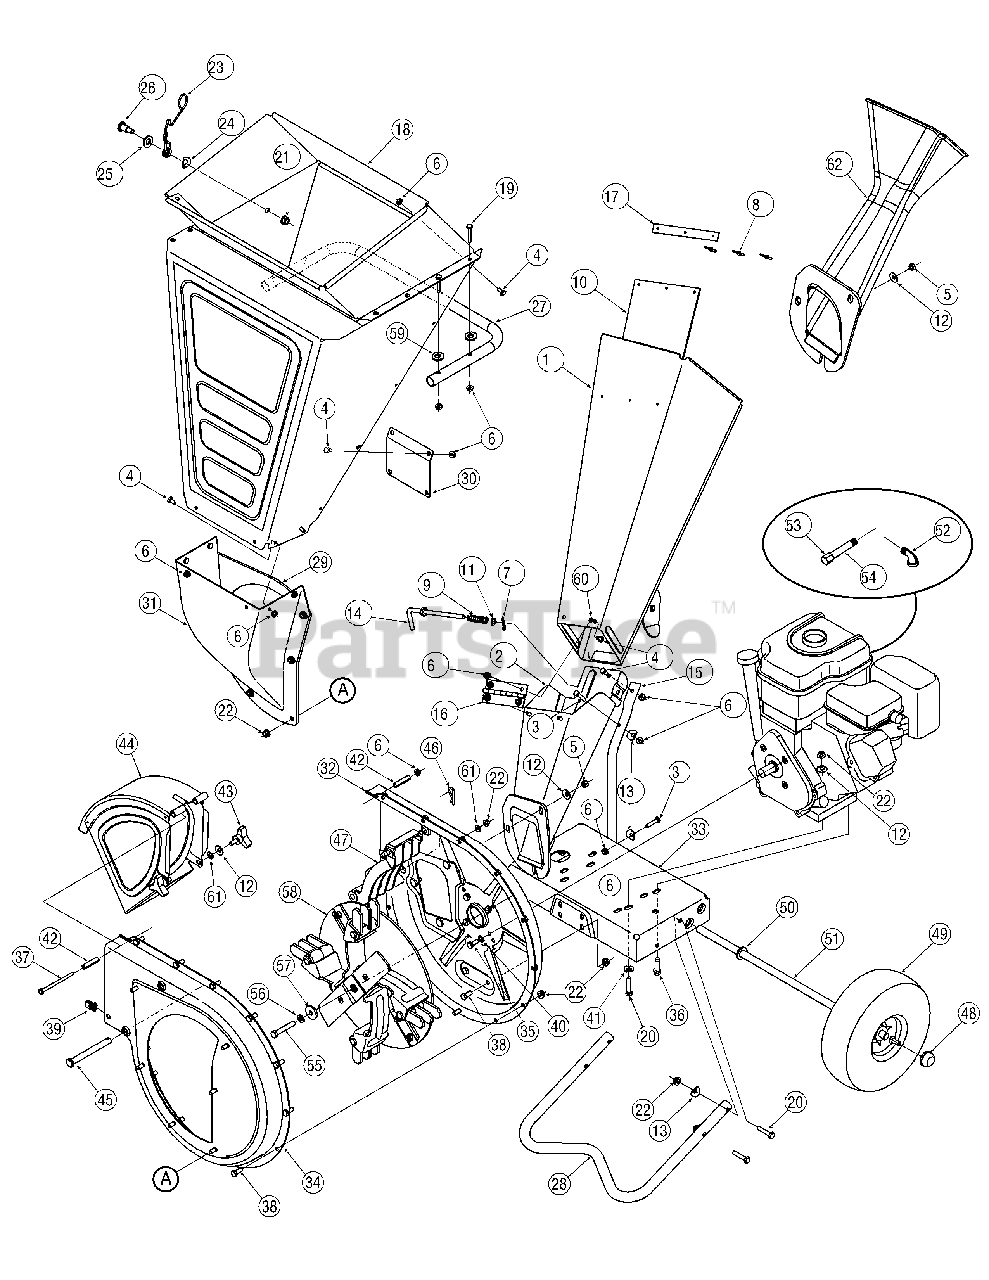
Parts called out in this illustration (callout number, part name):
3	Hex Cap Screw, 1/4-20 x 1.25
4	TT Screw, 1/4-20 x.5
5	Hex Nut, 5/16-18
6	Hex Lock Nut 1/4-20
7	Cotter Pin
8	Pop Rivet
9	Compression Spring,.531 x 1.75
10	Chute Flap
11	Flat Washer
12	Bell Washer.340 ID x.872 OD
13	Washer,.320 ID x.93 OD
14	Lock Rod
16	Chipper Chute Hinge
17	Chute Flap Strip
19	Hex Cap Screw, 1/4-20 x 1.250
20	Hex Cap Screw, 5/16-18 x 1.50
21	Flange Lock Nut, 3/8-16
22	Flange Lock Nut, 5/16-18
23	Torsion Spring
24	Spring Washer,.50 x 1.0 x.022
25	Flat Washer,.50 x 1.0 x.0125
26	Shoulder Screw, 3/8-16,.50 x.685
35	Hex Cap Screw, 5/16-24 x.75
36	Hex Sems Screw, 3/8-16 x 1.25
37	Hex Cap Screw, 1/4-20 x 3.75
38	Hex Cap Screw, 5/16-18 x.625
39	U-Nut, 5/16-18
40	Lock Washer, 5/16
41	Special Lock Washer, 5/16
42	Hinge Spacer,.265 x.380 x 1.66
43	Knob Assembly (Incl. ref.# 12 & 61)
43	Knob Only, 5/16-18
45	Clevis Pin,.50 x 4.62
46	Internal Cotter Pin
47	Shredder Screen
48	Push Cap, 5/8
49	Wheel, 10 x 4 x 4
50	Flat Washer,.625 x 1.0
51	Axle, 22.47"
52	Elbow Fitting
53	Oil Drain End Cap
54	Oil Drain Pipe
55	Hex Cap Screw, 3/8-24 x 2.2
56	Lock Washer, 3/8
57	Flat Washer,.406 x 1.25
58	Impeller Assembly
59	Flat Washer,.28 x.74 x.063
60	Push Nut,.25ID x.50OD
61	Speed Nut,.3125ID
63	Nut, Flange, Lock, 5/16-18
